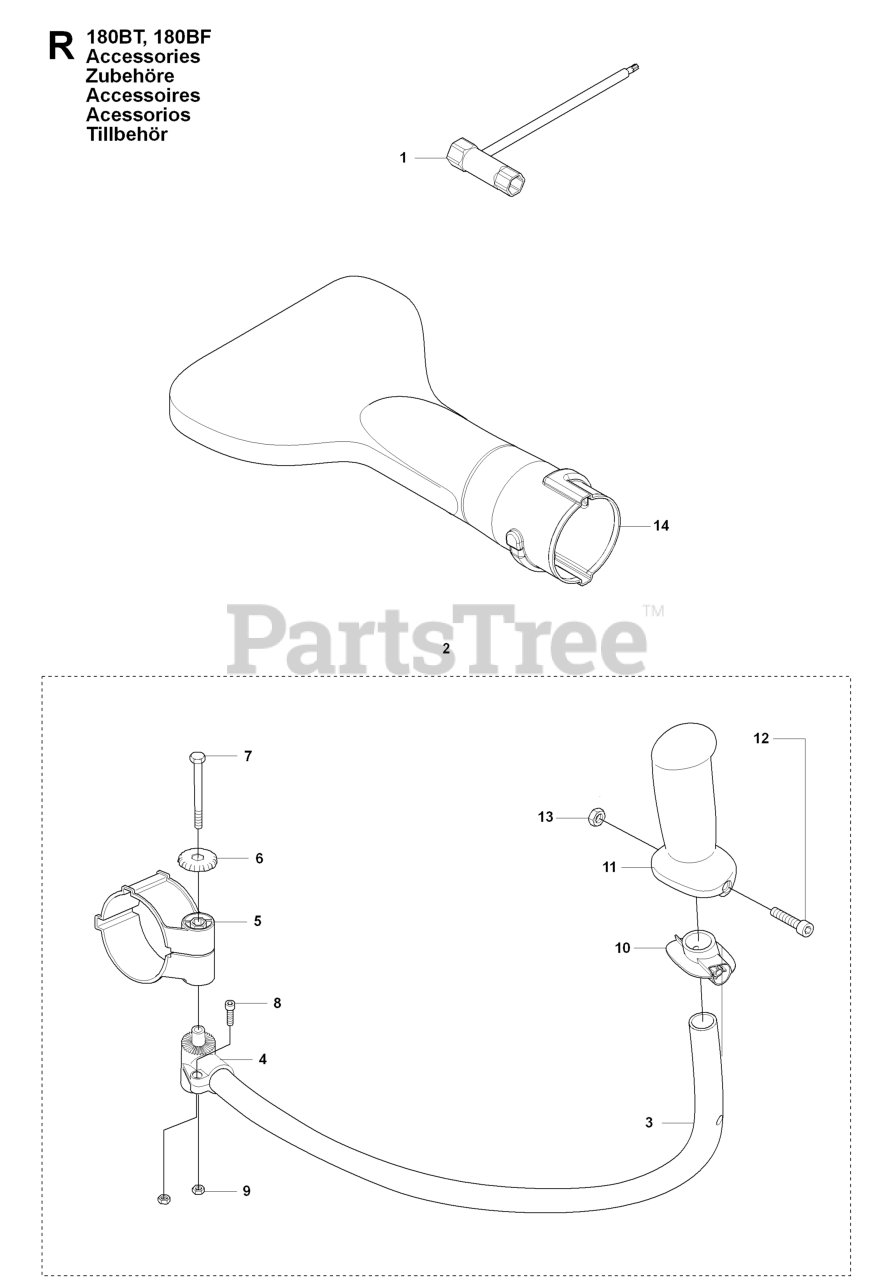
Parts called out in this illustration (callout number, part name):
1	SOCKET
2	HANDLE 170 BT
5	HOLDER TH
8	SCREW MC6S 5X10
14	FLAT NOZZLE
